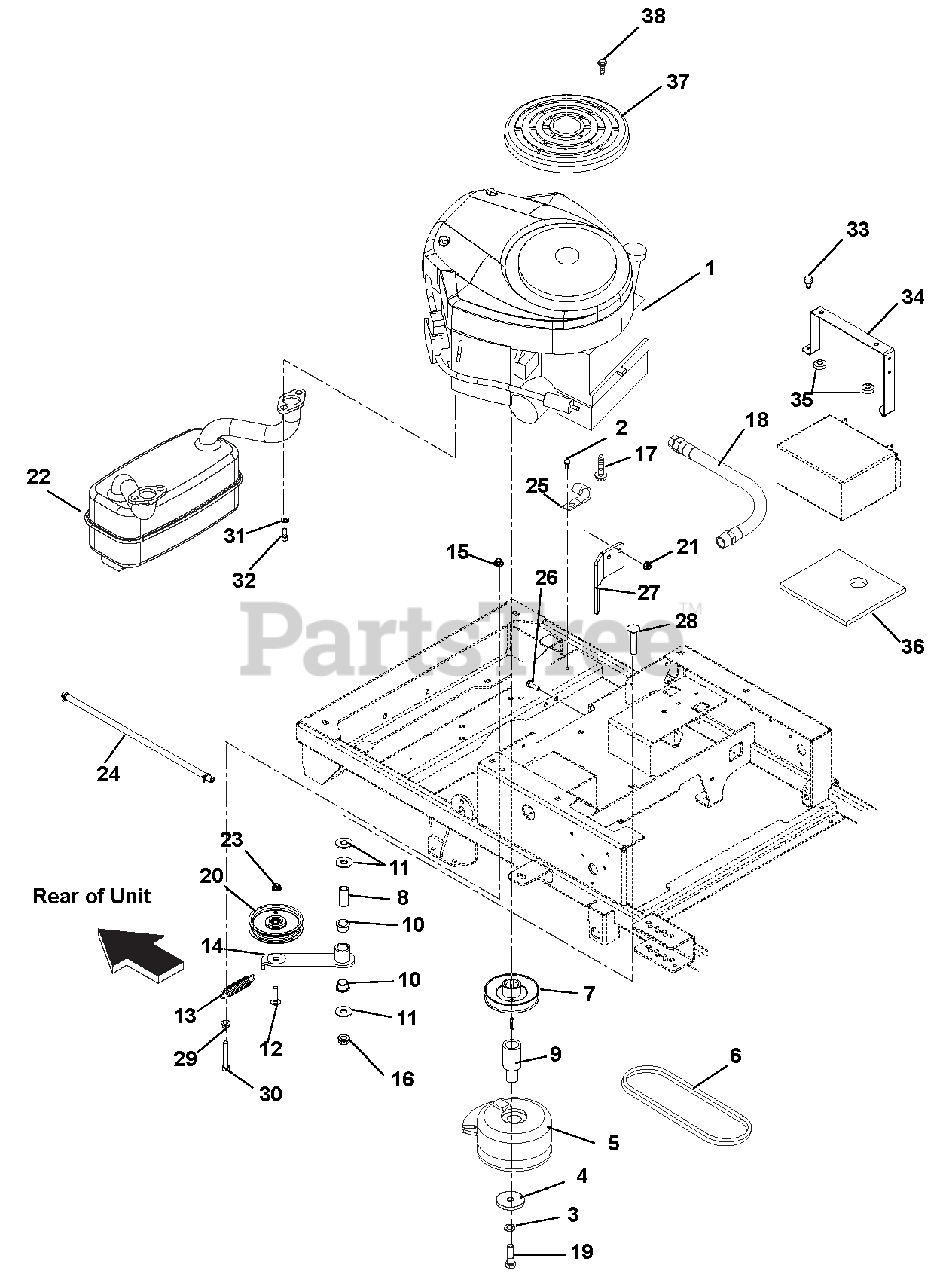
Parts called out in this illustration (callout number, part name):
1	ENGINE, 20HP COURAGE TWIN
1	ENGINE, COURAGE 25HP
1	ENGINE, 18HP V-TWIN CE
2	@SCR-TAP .25-20X.37 HWH YWZ TR
3	@WSHR-LK .44X.109 REG YWZC
4	WSHR-FL-STL .469X2.00X.25 YWZC
5	CLUTCH, MS
5	CLUTCH, MS WITH BRAKE
6	V-BELT, HA-WRAPPED
7	PLY-V 4.5X1.5 AB SECTION W/KEY
8	BSHG-SLV .500X.750X1.560
9	EXT-CRANKSHAFT LOWER
10	BSHG-FLG 0.75X0.875X.625X1.125
11	@WSHR-FL-STL.563X1.38X.109YWZC
12	@BLT-RDHDSQNK .38-16X1.50 G5YZ
13	SG-TENS .105X.812X3.88 WLD 15
14	WMT, GROUND DRIVE IDLER ARM
15	@NUT-LK-NYL-FLG .38-16 YWZC
16	@NUT-LK-TOP-FLG .50-13 YWZC
17	@SCR-TAP .38-16X1.00 HWH TR YZ
18	HOSE, HYD .38-11-0K M6N0-F6J0
19	BLT-HEX .44-20X4.50 GR8 YWZC
20	ASM, 4" IDLER (.75 WIDE)
21	@NUT-LK-NYL-FLG .31-18 YWZC
22	MUFFLER
22	MUFFLER - TWIN BRIGGS
23	@NUT-LK-TOP-FLG .38-16 YWZC
24	ASM, FUEL HOSE
25	J-CLAMP
26	@BLT-HEX .31-18X1.00 GR5 YWZC
27	CLUTCH STOP
28	@BLT-RDHDSQNK .50-13X2.50 G5YZ
29	@NUT-SPNLK-FLG .375-16 YWZC
30	@BLT-HEX .38-16X2.50 GR5 YWZC
31	@WSHR-LK .31X.078 REG YWZC
32	SCR-CAP .31-18X.75 S/HD
33	SCR-TAP.250-20X.62 HWH BLK ZC
34	STRAP, BATTERY
35	BUTTON BUMPER
36	MAT, BATTERY
37	GUARD, BRIGGS ENGINE
38	SCREW, 8-16X.87 PHPAN 3 LOBE
